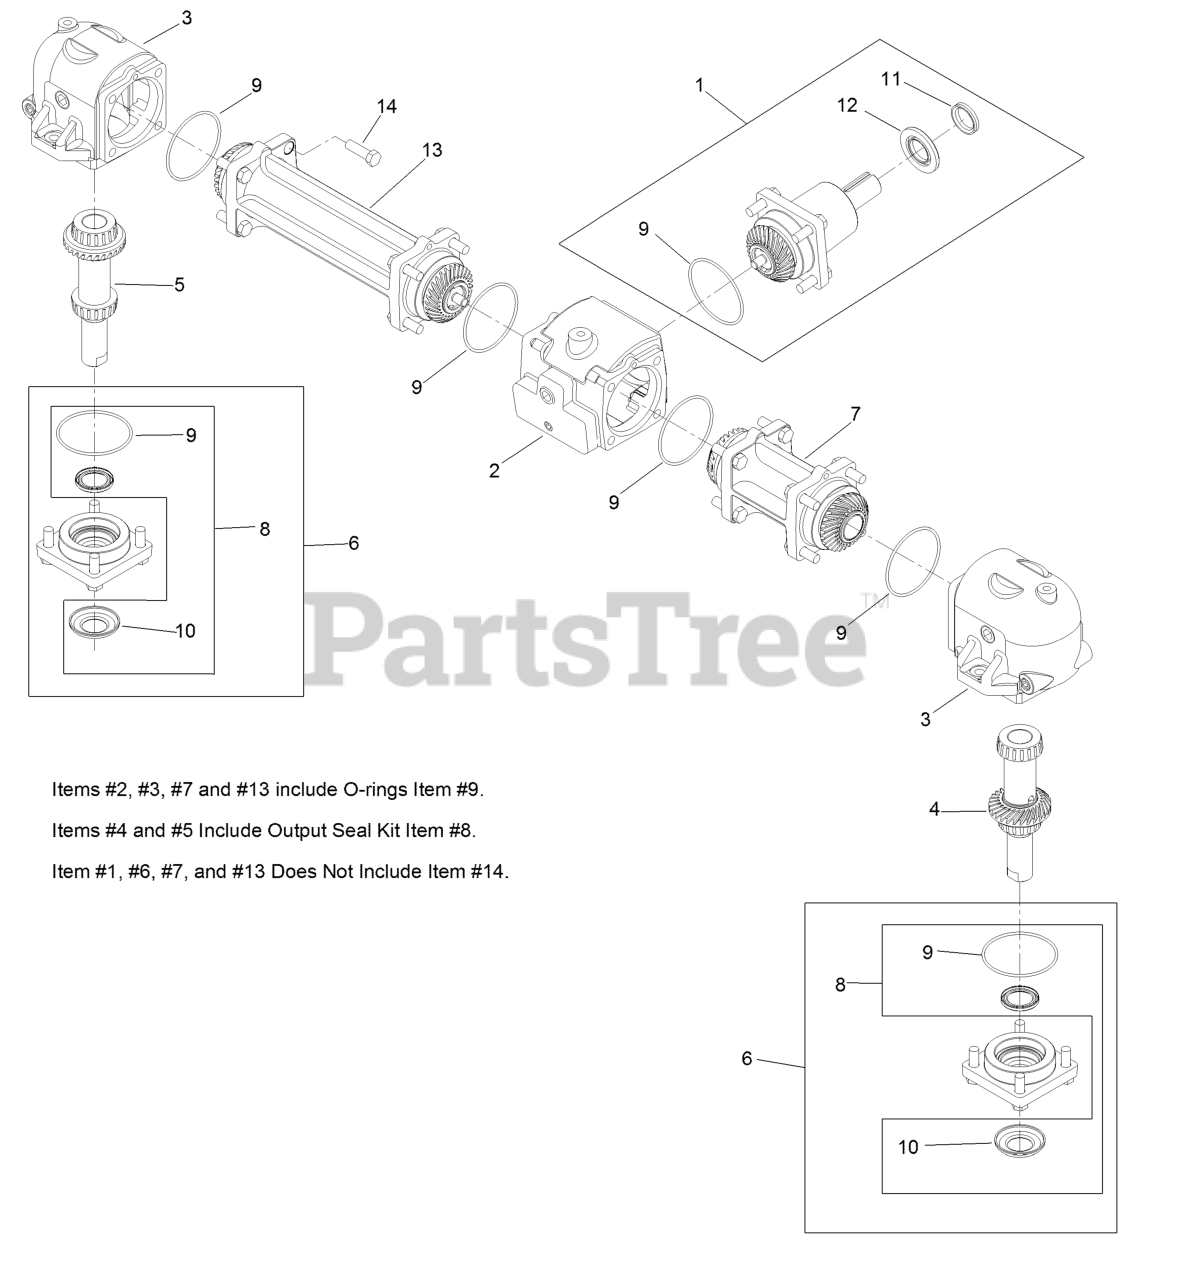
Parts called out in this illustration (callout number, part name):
1	Pinion-Input
2	Housing-Center
3	Housing-End
4	Output Shaft And Gear-LH
5	Output Shaft And Gear-RH
6	Cap-Output
7	Tube-Connector, Shor
8	Output Seal Kit
9	Seal-O-Ring
10	Washer-Cupped
11	Seal-V-Ring
12	Seal-Input
13	Connector-Tube, Long
14	Bolt-Blade
